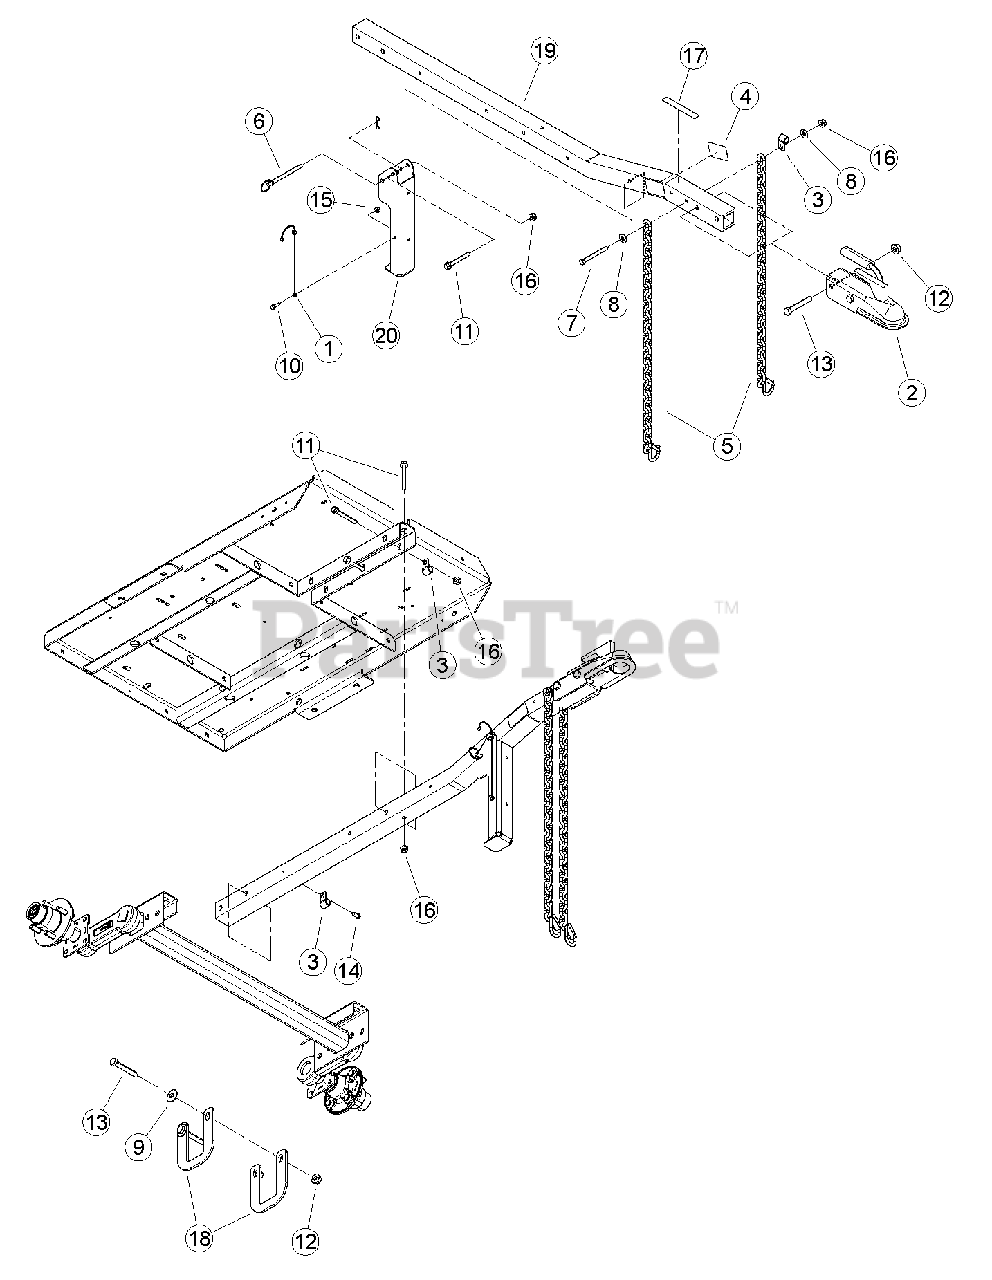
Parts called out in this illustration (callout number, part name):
1	LANYARD, NYLON
2	COUPLER, 50 MM BALL
3	CLAMP, 9/16 COATED
4	REFLECTOR, WIDE ANGLE AMBER
5	CHAIN, SAFETY 5000 LB W/ LATCH
6	PIN, 3/8 HITCH
7	BOLT, 3/8 X 3-1/2" HEX HD GR5 ZP
8	WASHER, 3/8 FLAT
9	WASHER, 1/2 FLAT
10	BOLT, 1/4-20 X 3/4 FLANGE GR5 CZP
11	BOLT, 3/8 X 3 FLANGE NC
12	NUT, 1/2-13 NYLOCK FLANGE
13	BOLT, 1/2 X 3-1/4 HCS GR5 ZP
14	SCREW, 11/32-12 X 7/8 FLANGE T-AB
15	NUT, 1/4-20 NYLOCK FLANGE
16	NUT, 3/8-16 NYLOCK FLANGE
17	DECAL, HITCH LOAD
18	PLATE, HITCH SADDLE
19	POLE, C/S HITCH
20	WELDMENT, STAND JACK
